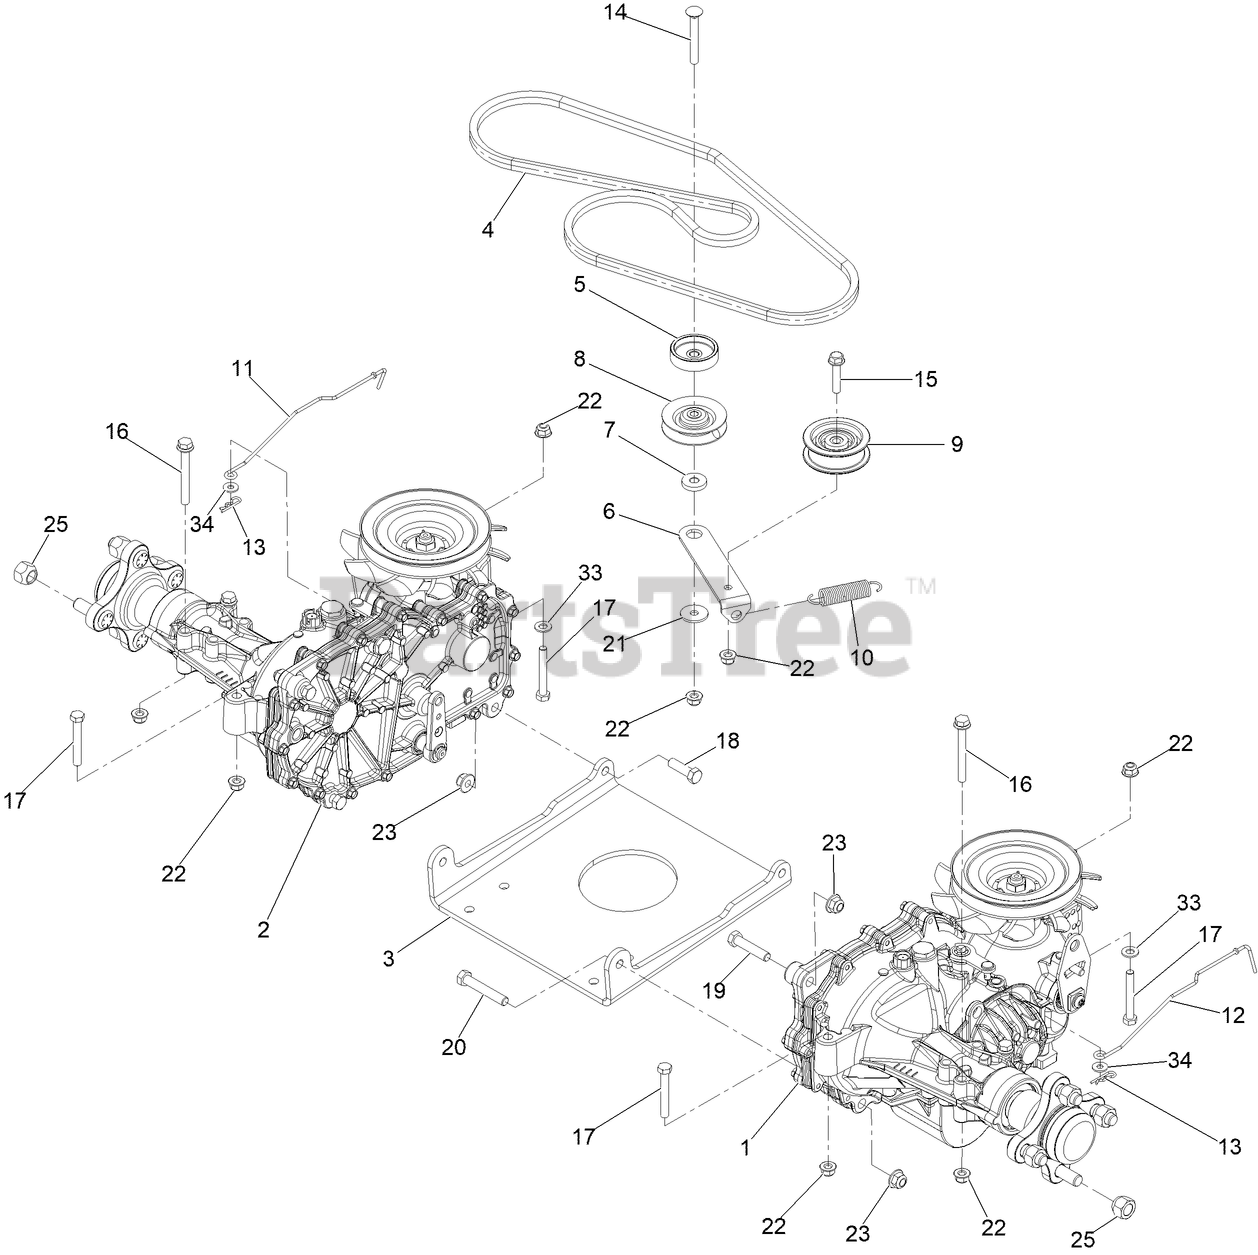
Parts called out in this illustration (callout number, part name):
1	LH Hydro Transmission ASM
2	RH Hydro Transmission ASM
3	PLATE- HYDRO
4	V-BELT
6	Arm-Idler
7	SPACER-ARM, IDLER
9	Pulley-Idler, Flat
10	Spring-Return, Pedal
11	ROD-BYPASS, RH
12	ROD-BYPASS, LH
14	SCREW-CARR
15	SCREW-HHF
16	SCREW-HHF
17	SCREW-HH
18	SCREW-HH
19	SCREW-HH
20	SCREW-HH
21	WASHER-PIVOT
22	NUT-HF, NI
23	NUT-HF, NI
25	NUT-LUG
33	WASHER-PLAIN
